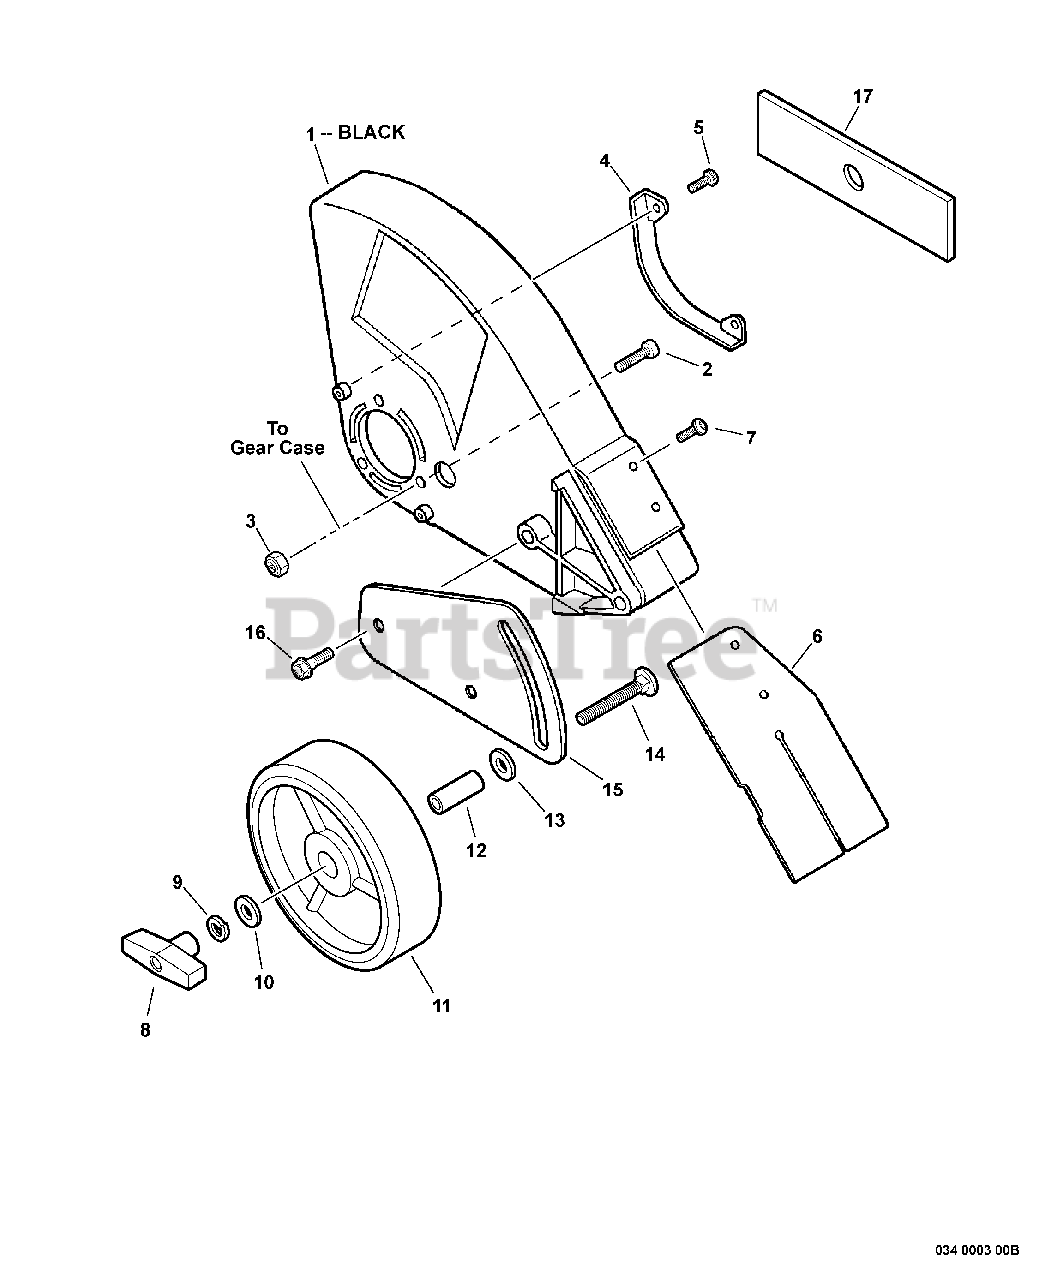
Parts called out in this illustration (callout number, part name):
1	SHIELD, DEBRIS
2	BOLT, TORX 5×20
3	NUT, LOCK M5
4	GUARD, SHIELD
5	BOLT, TORX 4×16
6	FLAP, DEBRIS
7	BOLT, TORX 4×20
8	KNOB, FASTENER
9	WASHER, SPRING 8
11	WHEEL
12	COLLAR 12
13	WASHER, SPRING 10
14	BOLT 5/16"-18×2-1/2"
15	BRACKET, WHEEL
17	BLADE - 2 PK
